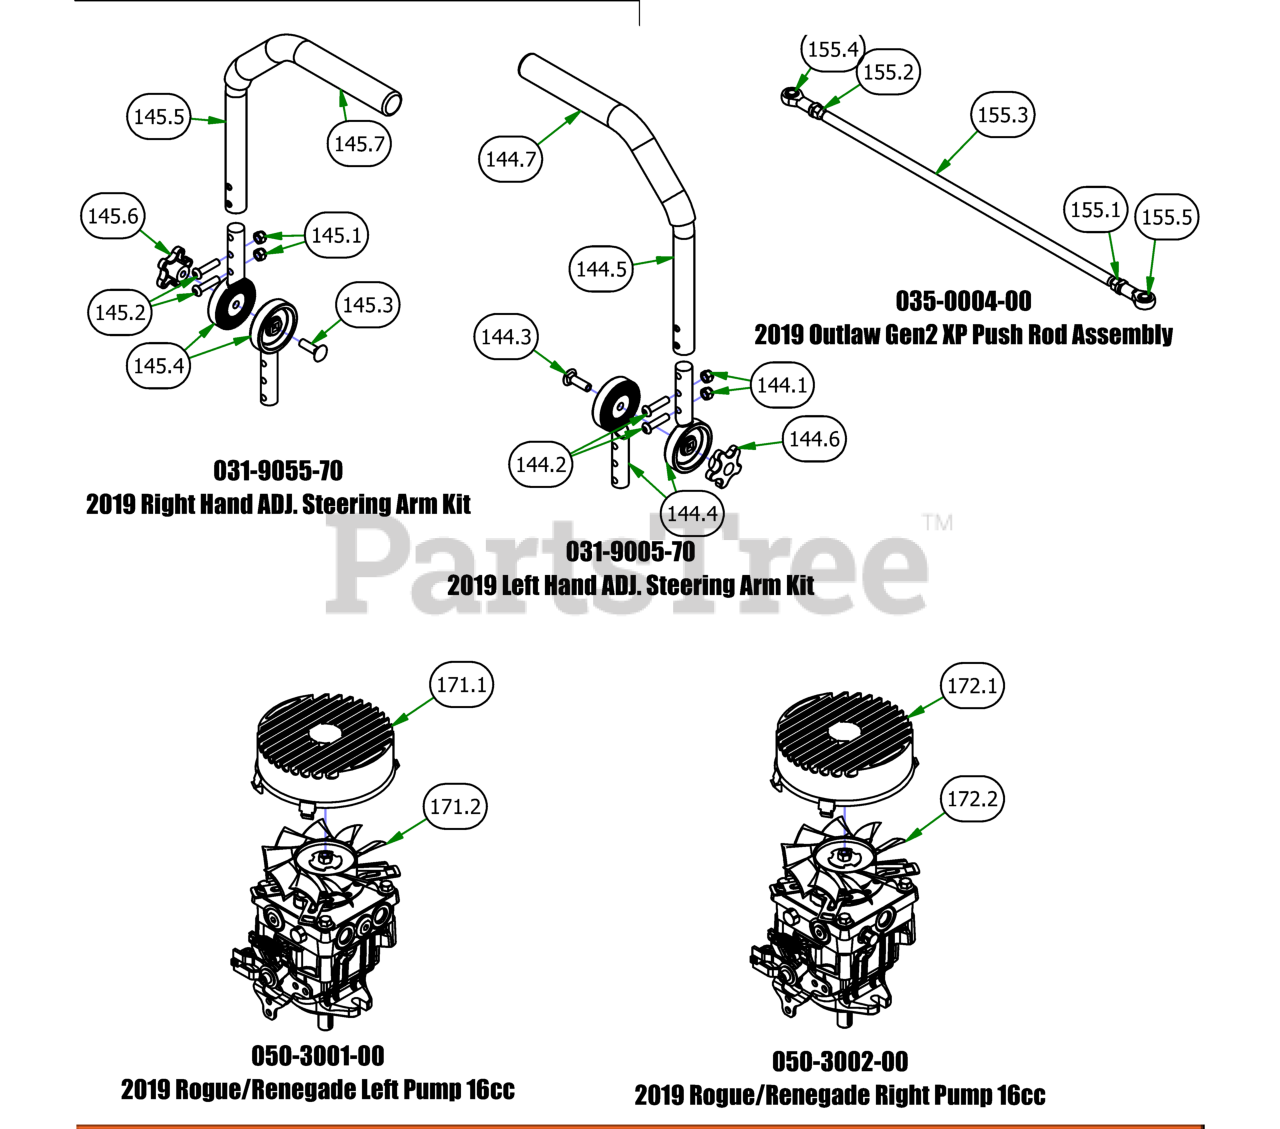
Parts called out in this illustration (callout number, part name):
144.1	5/16-18 Nylock Insert Locknut
144.2	5/16-18 UNC X 1-3/8" BHCS, TORX DRIVE, GR 5
144.3	3/8" x 1 1/4" Carriage Bolt
144.4	2019 Steering Arm Adjuster Casting
144.5	2019 Steering Arm Grip
144.6	Black Knob for Adjustable Steering Arm
144.7	Black Steering Arm Grip
145.1	5/16-18 Nylock Insert Locknut
145.2	5/16-18 UNC X 1-3/8" BHCS, TORX DRIVE, GR 5
145.3	3/8" x 1 1/4" Carriage Bolt
145.4	2019 Steering Arm Adjuster Casting
145.5	2019 Steering Arm Grip
145.6	Black Knob for Adjustable Steering Arm
145.7	Black Steering Arm Grip
155.1	5/16" RH Fine Threaded Jam Nut
155.2	5/16" LH Fine Threaded Jam Nut
155.3	2019 Outlaw Gen2 Xp Rod
155.4	Spherical Rod End - Outlaw
155.5	Spherical Rod End - Outlaw
171.1	Fan Guard 6" Fits wheel Motor Pumps
171.2	Hydraulic Fan
172.1	Fan Guard 6" Fits wheel Motor Pumps
172.2	Hydraulic Fan
